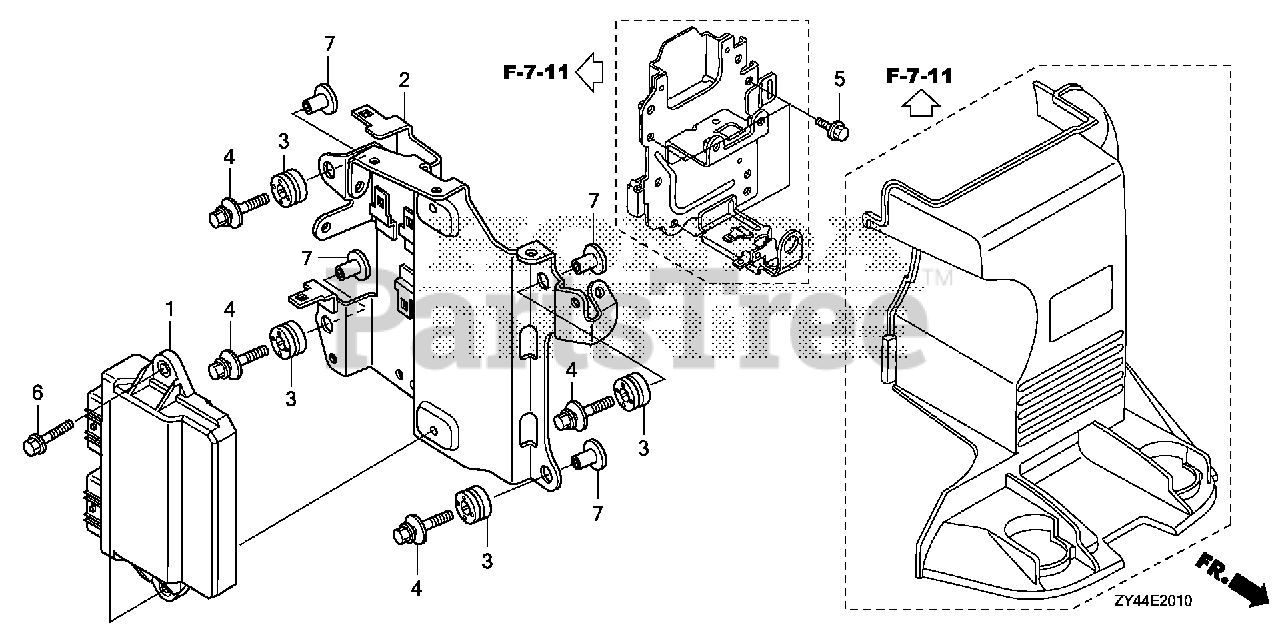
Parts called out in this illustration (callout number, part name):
1	CONTROL UNIT, ELECTRONIC
2	BRACKET, ECU
3	GROMMET, RELAY BRACKET
4	BOLT-WASHER (6X27) (CT200)
5	BOLT, FLANGE (6X14) (CT200)
6	BOLT, FLANGE (6X20)
7	COLLAR, MODULE IGNITION CONTROL CASE (CDI)
